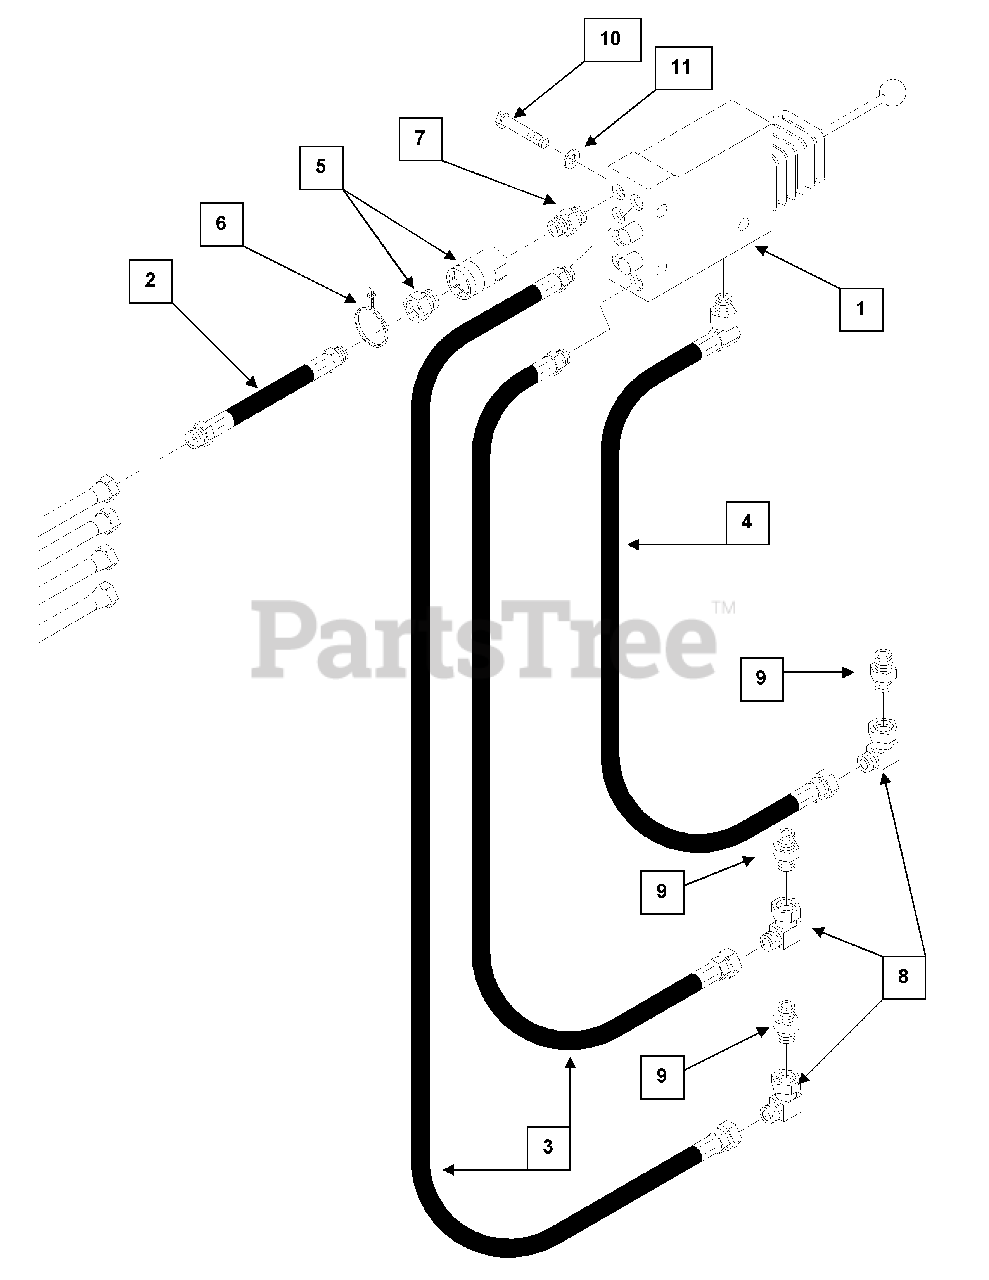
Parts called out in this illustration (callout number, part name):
1	Hydraulic Control Valve
2	Hydraulic Hose Assembly, 3/8" x 36"
3	Hydraulic Hose Assembly, 3/8" x 48"
4	Hydraulic Hose Assembly, 3/8" x 46"
5	Quick Coupler, 3/8" (complete with both ends)
6	Color Code Tie Strap, Blue
7	Hydraulic Adapter
8	Hydraulic Adapter, 90?
9	Hydraulic Adapter
10	Hex Head Cap Screw, 5/16" x 3/4"
11	Lock Washer, 5/16"
